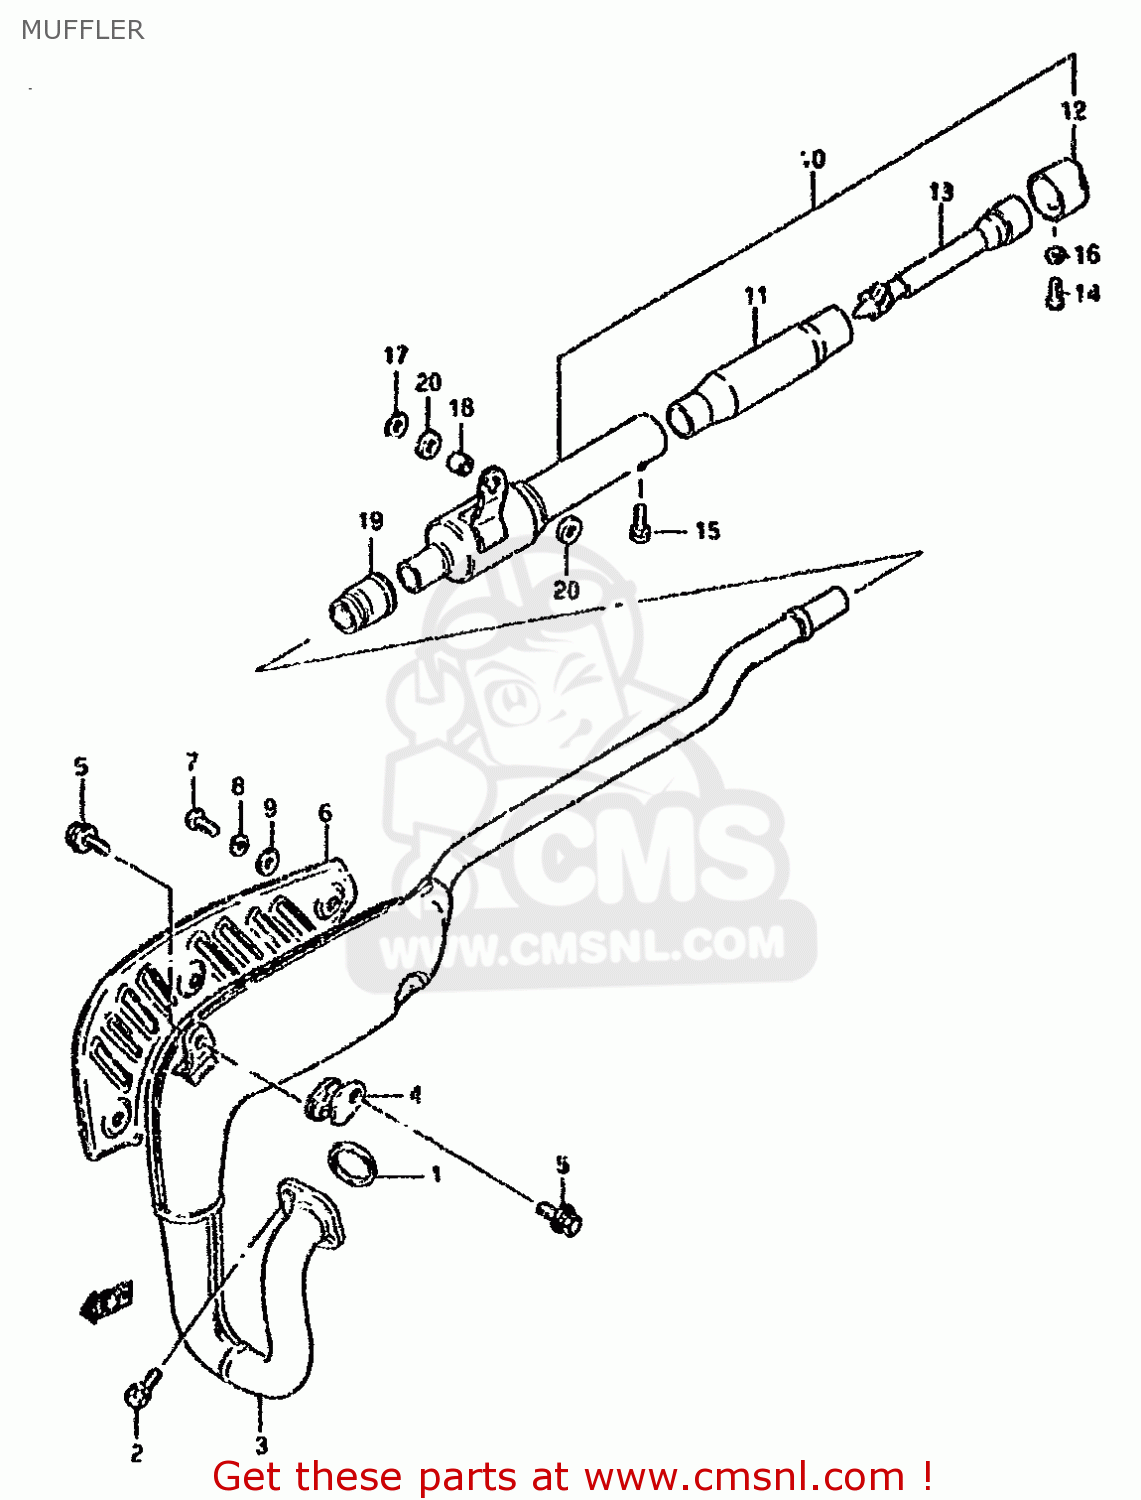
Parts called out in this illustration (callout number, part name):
1	GASKET,EXHAUST (NAS)
2	BOLT
3	BODY,MUFFLER 1ST
4	DAMPER,MUFFLER SUPPORT
5	BOLT
6	COVER,MUFFLER
7	SCREW
8	WASHER,LOCK
9	WASHER
10	MUFFLER ASSEMBLY
11	SHELL,ARRESTER
12	CUTTER,MUFFLER TAIL
13	TUBE,CLEAN OUT
14	SCREW
15	SCREW
16	WASHER,LOCK
17	WASHER
18	SPACER (8.6X13.8X9)
19	CONNECTOR,MUFFLER
20	CUSHION
